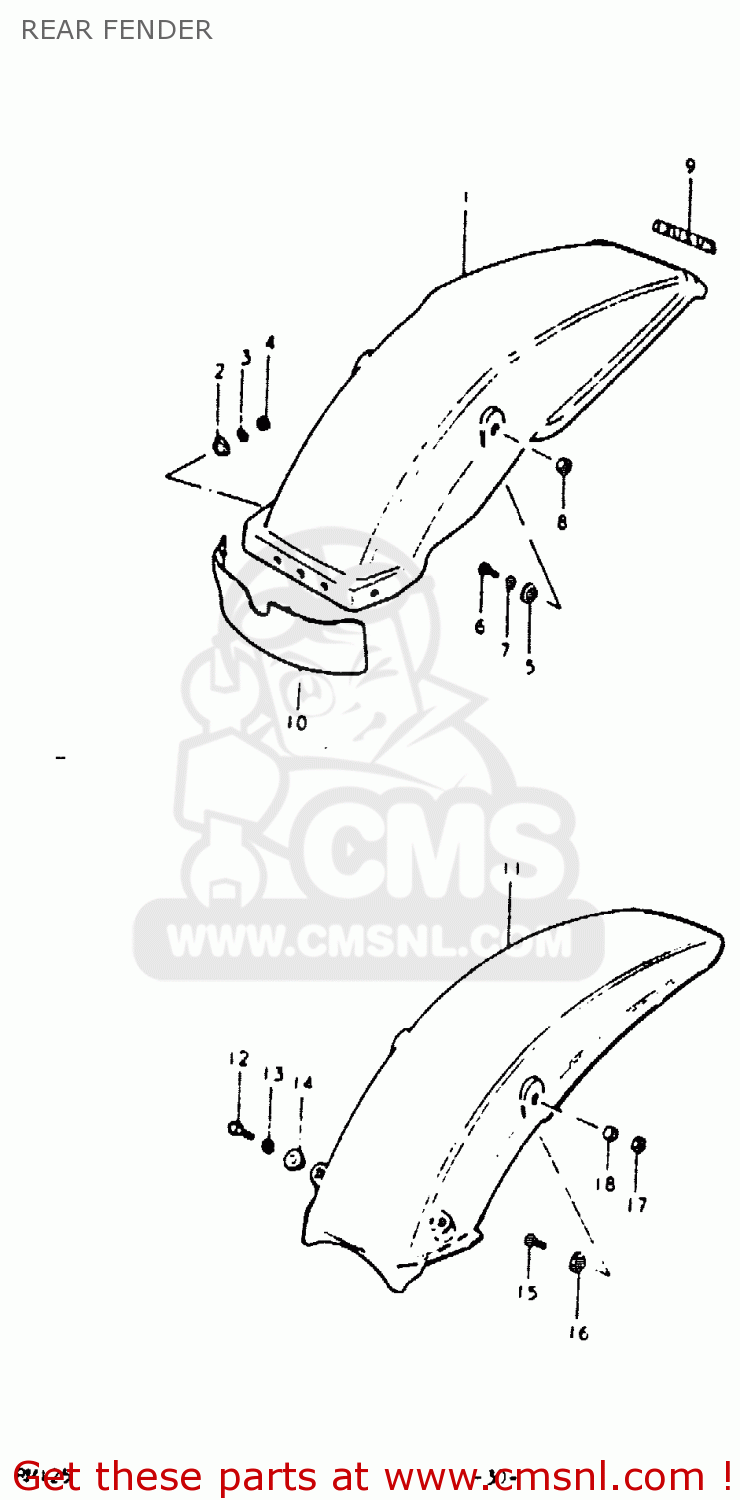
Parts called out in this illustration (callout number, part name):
11	FENDER,REAR
12	BOLT, UPPER
13	LOCK WASHER
14	WASHER
15	SCREW
16	WASHER (6.5X20X1.2)
17	NUT
18	SPACER
